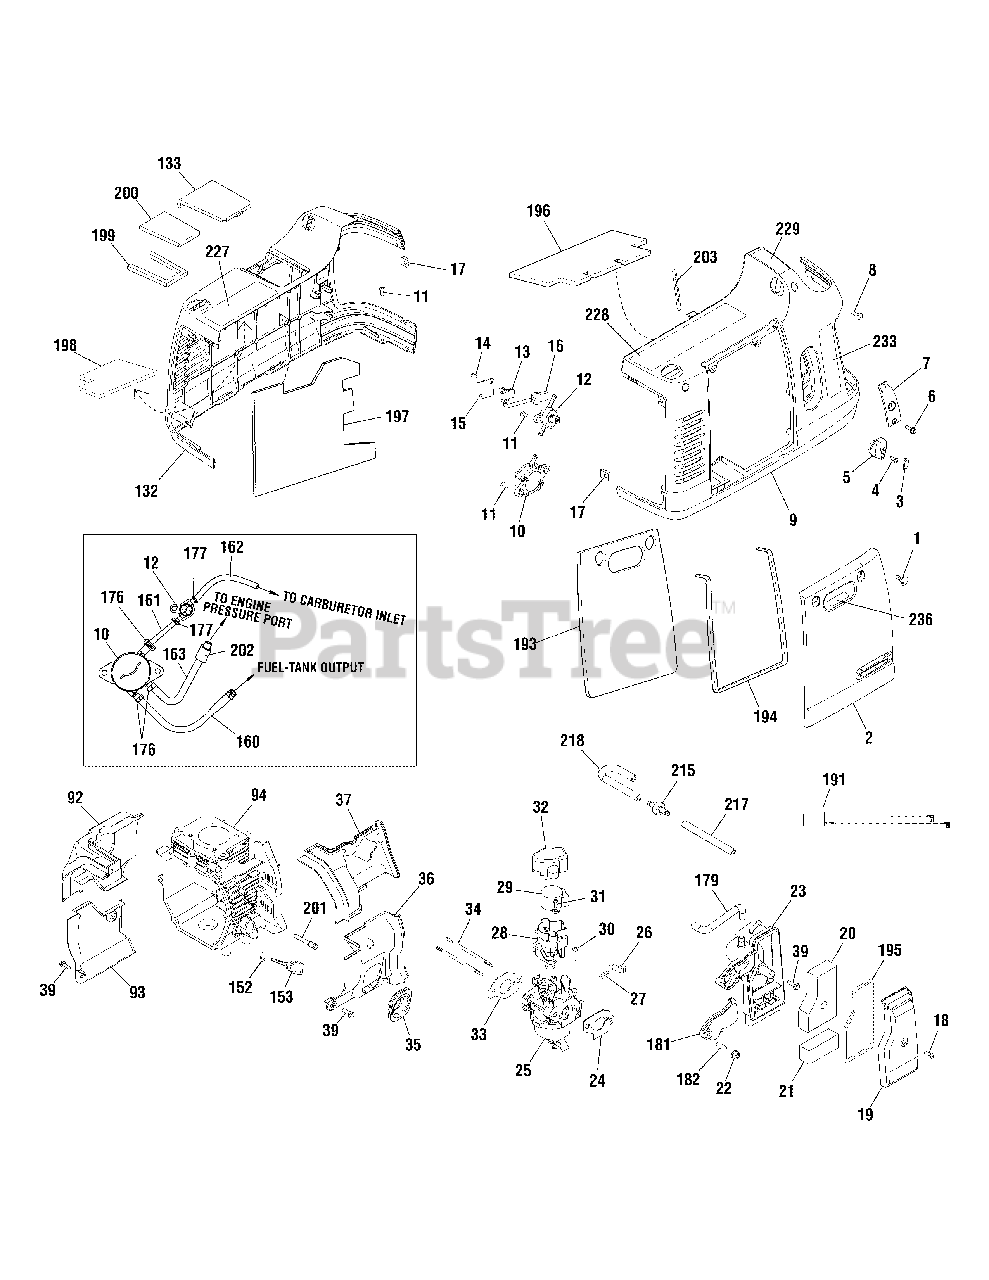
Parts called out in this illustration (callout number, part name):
2	PANEL-ACCESS
4	BOLT
9	COVER-SIDE
11	SCREW
14	BOLT
15	COVER-SWITCH
16	CONNECTION
17	NUT
19	COVER-AIR CLEANER
20	FILTER-A/C FOAM
21	FILTER-A/C FOAM
22	NUT
23	BASE-AIR CLEANER
24	GASKET-AIR CLEANER
27	SPRING
30	BOLT
31	BOLT
35	SEAL-RUBBER
36	DEFLECTOR
37	DEFLECTOR
92	DEFLECTOR
93	DEFLECTOR
94	CRANKCASE
132	COVER-SIDE
133	COVER-SPARK PLUG
176	CLAMP
177	CLAMP
181	COVER-AIR CLEANER
182	SLEEVE
193	FOAM
194	SEAL
195	SEAL
196	FOAM
197	FOAM
198	FOAM
199	SEAL
200	FOAM
201	CYLINDER-BREATHER TUBE
202	TUBE
203	BRACKET
